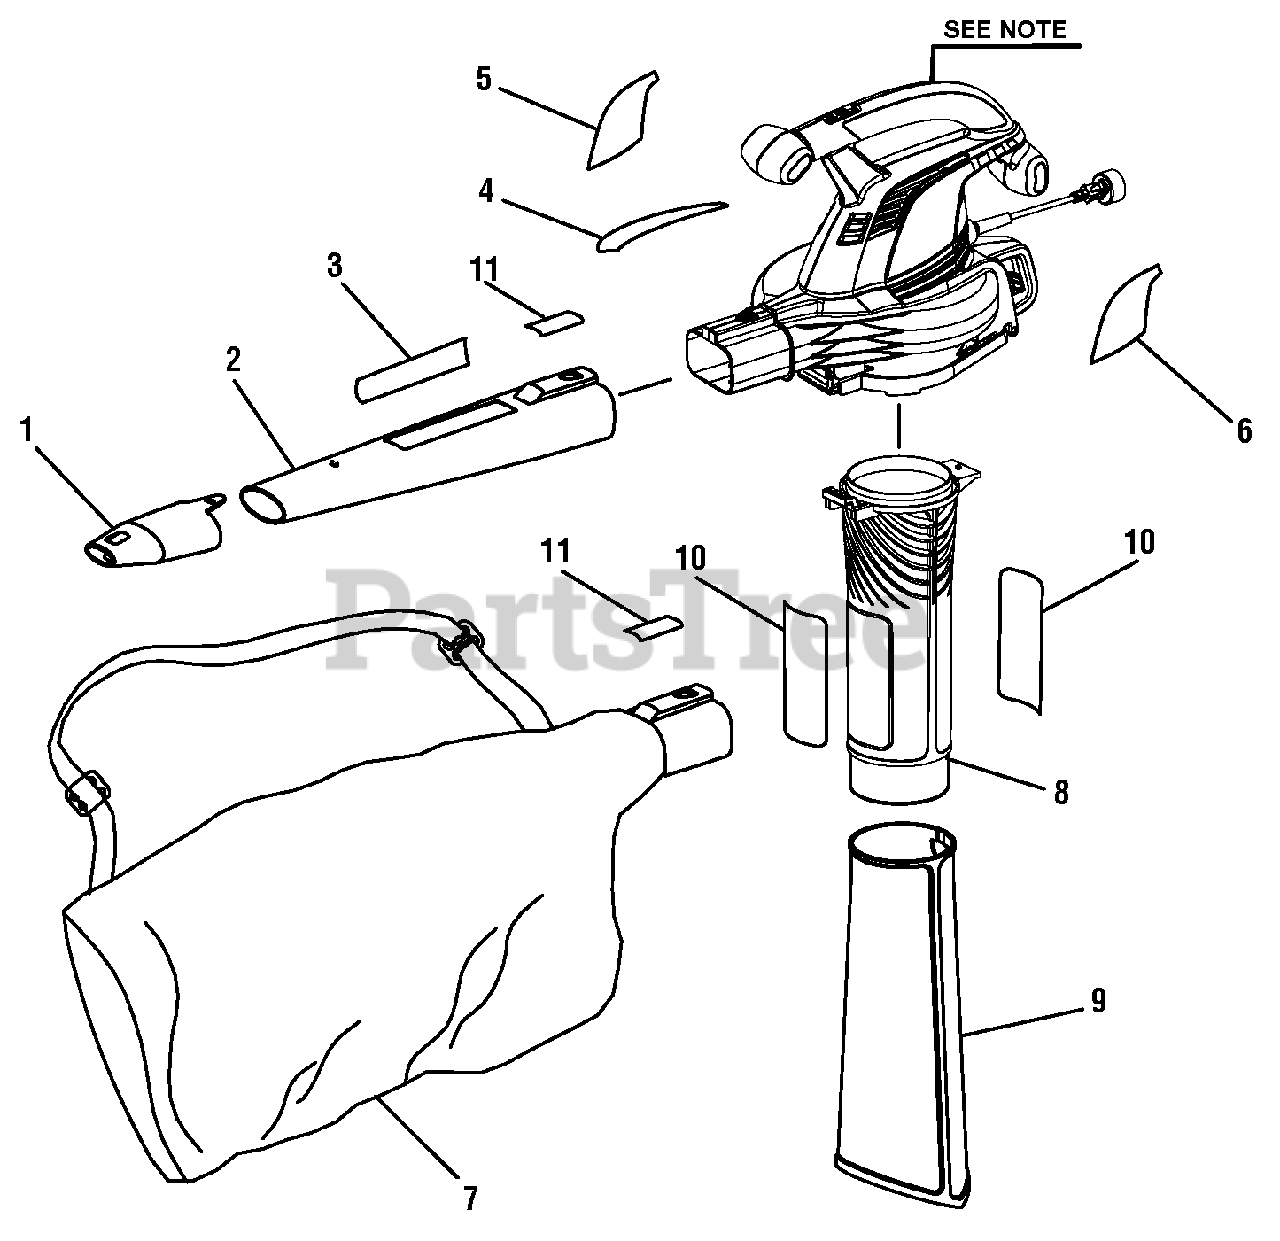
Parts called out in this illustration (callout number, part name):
1	High Velocity Nozzle
2	Blower Tube
3	Logo Label (Blower Tube)
4	Logo Label (Motor Housing, Right)
5	Warning Icon/Performance Label
6	Data Label
7	Vacuum Bag
8	Upper Vacuum Tube
9	Lower Vacuum Tube
10	Logo Label (Upper Vacuum Tube)
11	Caution Label
